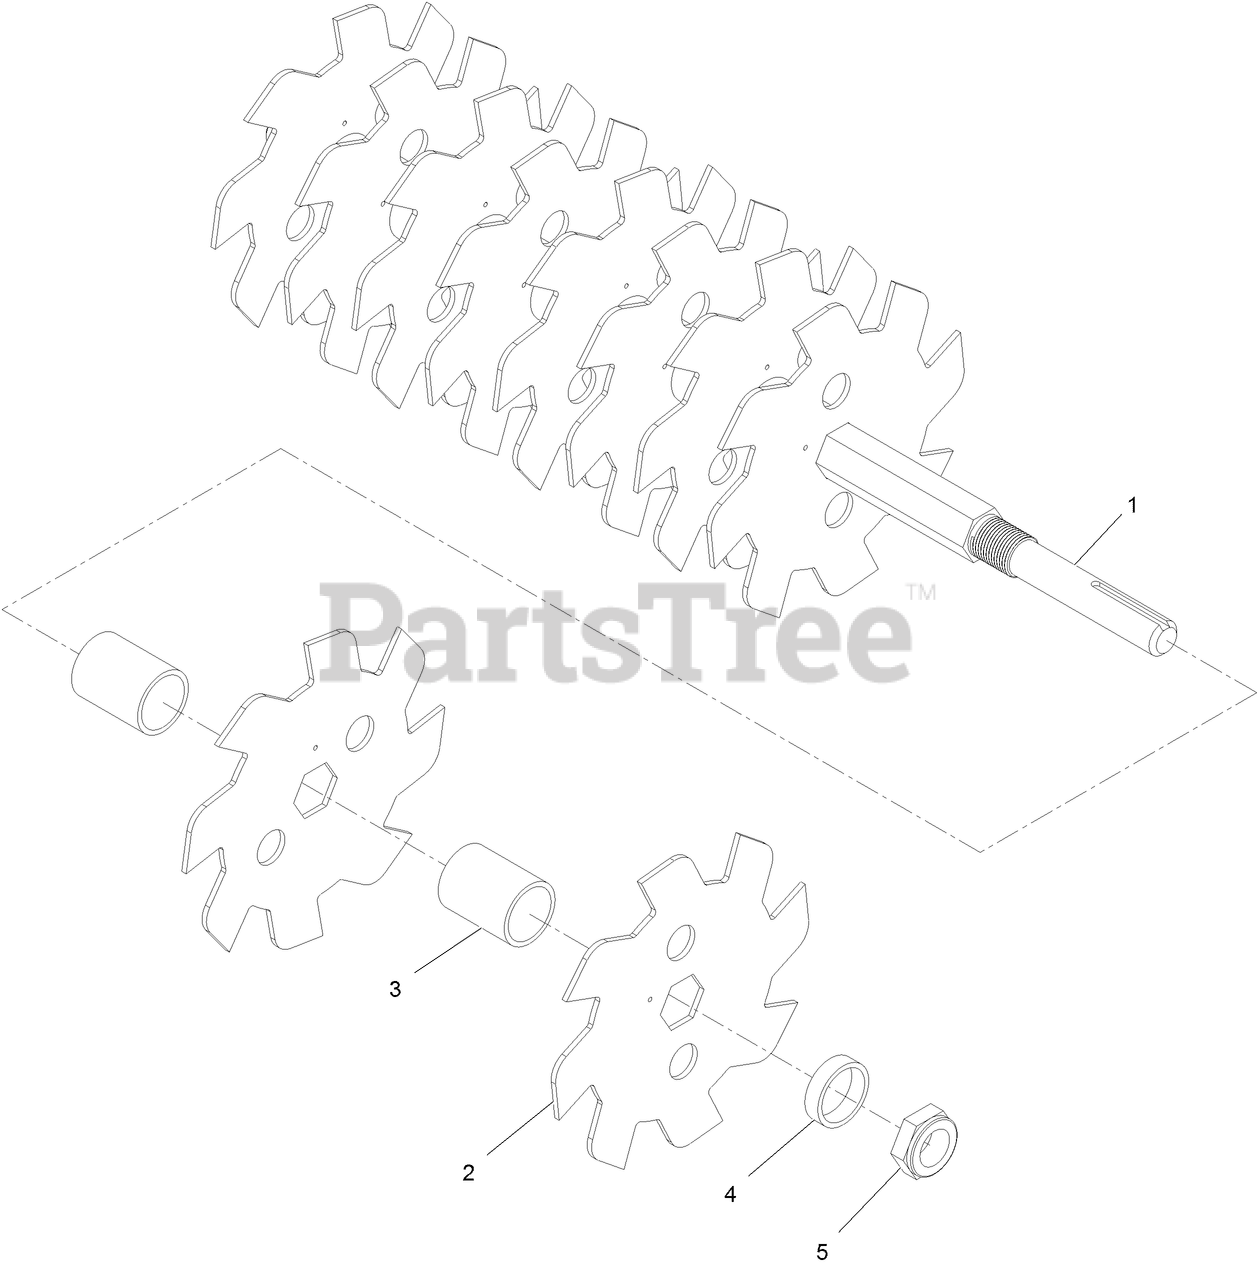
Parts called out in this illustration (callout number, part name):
1	SHAFT-SLICER
2	BLADE-CUTTING, SEEDER
3	SPACER-BLADE
4	SPACER
5	NUT-LOCK, NI
